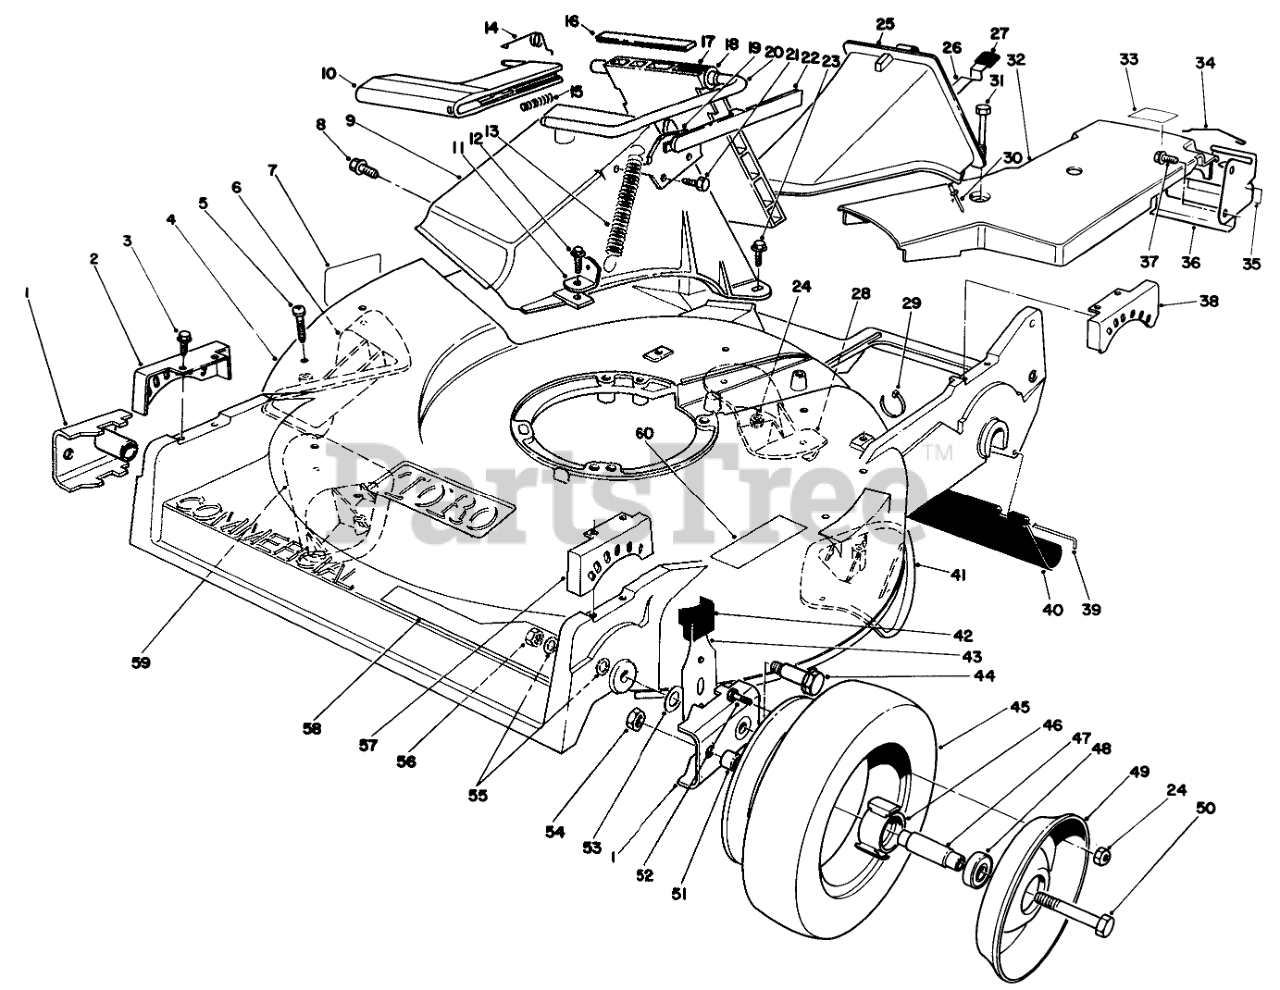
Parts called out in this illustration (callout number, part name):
1	ARM-PIVOT, FRONT
2	QUADRANT-FRONT, RH
3	SCREW-HWHTF
4	Housing-Commercial (Incl. Ref. #7, 58, & 60)
5	#8 X .625" PHILPS PAN H
6	KICKER
7	DECAL-DANGER
8	SCREW
9	DISCHARGE TUNNEL
10	Handle-Door
11	Bracket-Spring
12	SCREW-HWH
13	SPRING-DOOR
14	RETAINER-DOOR
15	Spring
16	Cover-Door
17	Door-Discharge
18	BUSHING-NYLON
19	DOOR LATCH PLATE
20	Rod-Door
21	SCREW-PLASTITE
22	Cover-Handle
23	SCREW-HH
24	NUT-LOCK, NI
25	Plug-Discharge (Incl. Ref. #26, 27, & 30)
26	LATCH-PLUG, DISCHARGE
27	GRIP-LATCH
28	KICKER
29	TIE-CABLE
30	RIVET-HEAD, FLAT
31	SCREW-HHFTF
32	COVER-BELT
33	LABEL-GREASE
34	RETAINER-CABLE
35	DECAL-POSITION, GEAR
36	BRKT-TRACTION ADJ.
37	SCREW-HWHTF
38	QUADRANT-REAR, LH
39	ROD-SHIELD
40	SHIELD-TRAILING
41	KICKER
42	KNOB-ARM
43	FRONT SPRING ARM ASM
44	WHEEL BOLT
46	HUB-BEARING
47	SPACER-BEARING
48	BEARING-WHEEL
49	Wheel-Half
50	SCREW-HH
51	SPACER-WHEEL
52	SCREW-HH
53	WASHER-THRUST
54	NUT-LOCK, CONE
55	WASHER
56	Nut
57	QUADRANT-FRONT, LH
58	DECAL - RECYCLER
59	KICKER
60	DECAL-INSTRUCTION, SAFETY
